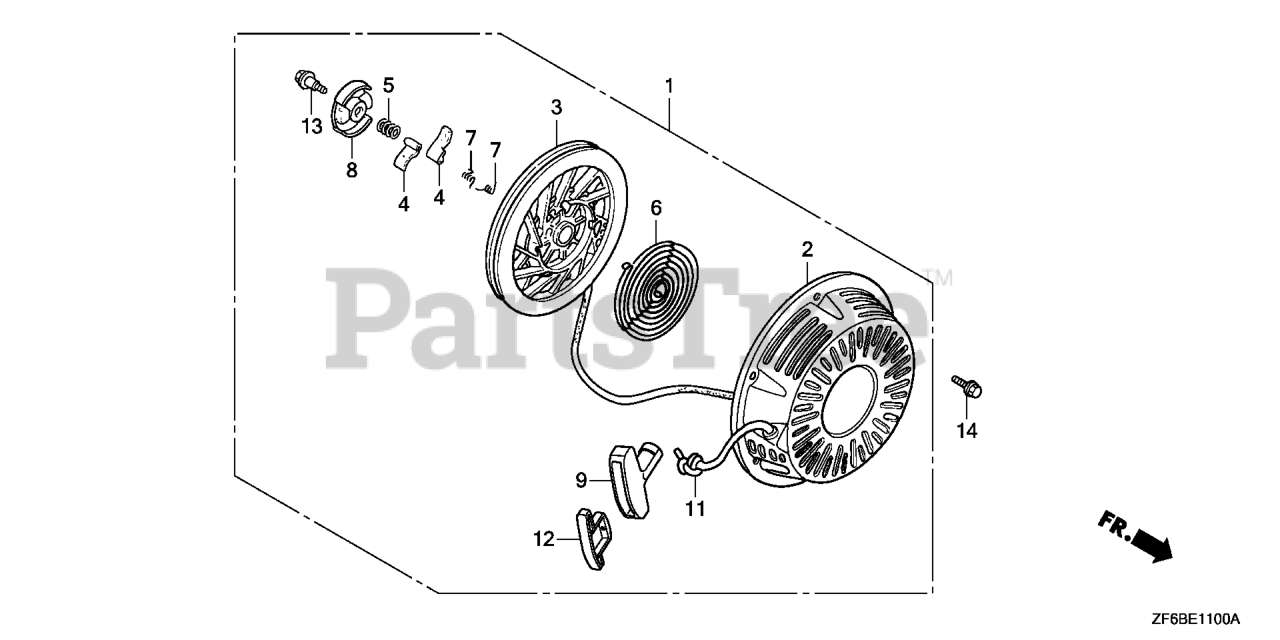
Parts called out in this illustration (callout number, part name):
1	STARTER ASSY., RECOIL *R280* (FOR U.S.A.) (POWER RED)
1	STARTER ASSY., RECOIL *NH1* (FOR U.S.A.) (BLACK)
2	CASE, RECOIL STARTER *NH1* (BLACK)
2	CASE, RECOIL STARTER *R280* (POWER RED)
3	PULLEY, RECOIL STARTER
4	RATCHET, STARTER
5	SPRING, FRICTION
6	SPRING, STARTER RETURN
7	SPRING, RATCHET
8	RETAINER, SPRING
9	GRIP, STARTER
11	ROPE, RECOIL STARTER (#6X64") (N/A: USE P/N 08560-ZG921-11)
12	GRIP, REINFORCEMENT
13	SCREW, CENTER
14	BOLT, FLANGE (6X10)
